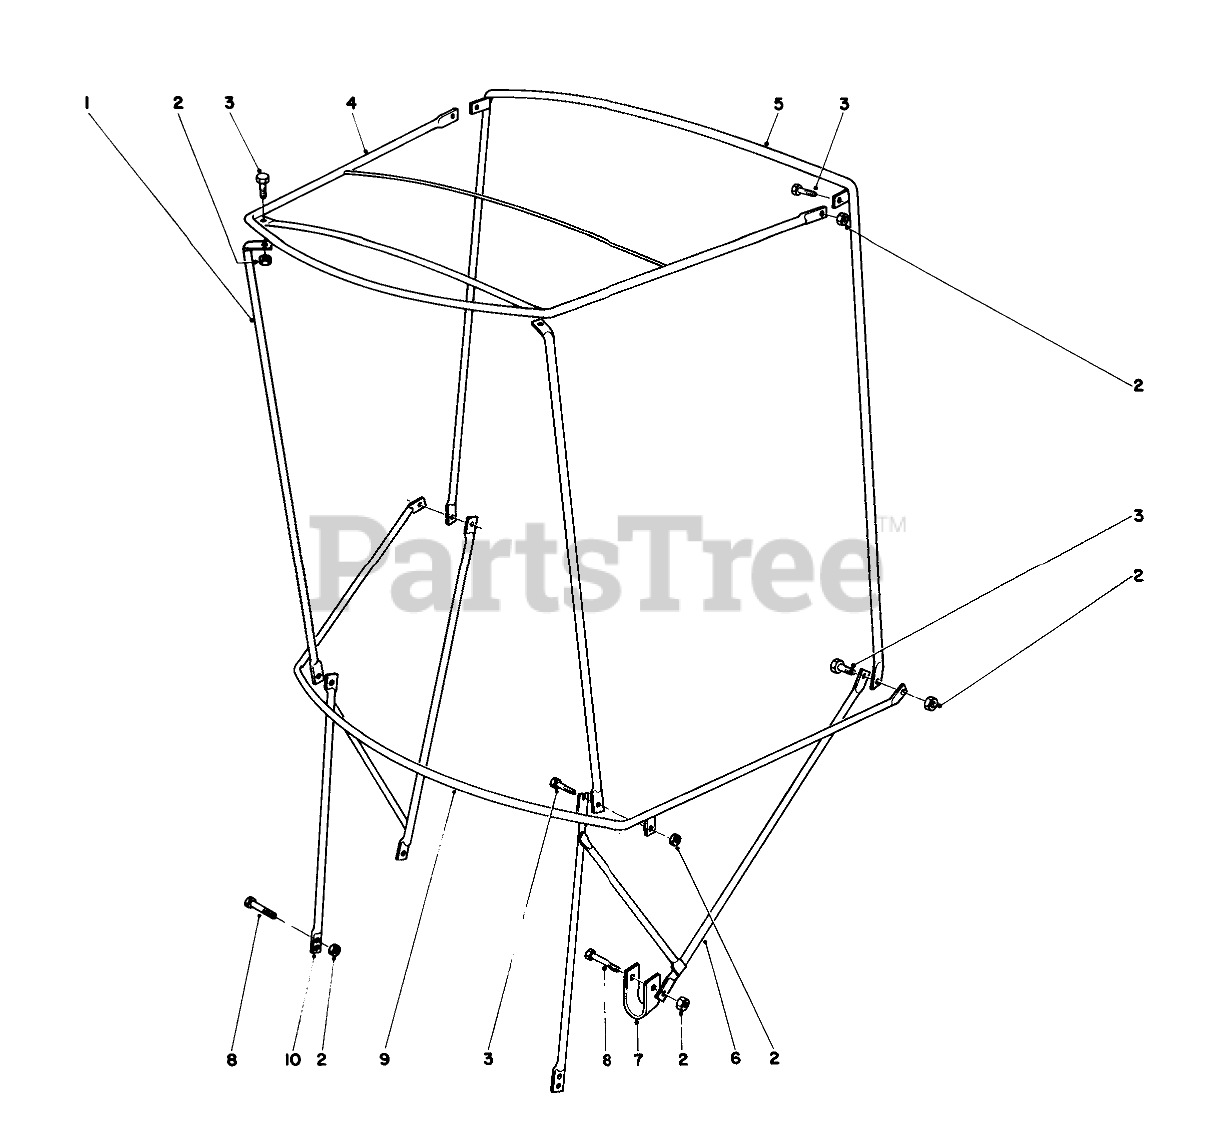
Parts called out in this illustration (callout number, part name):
2	NUT-LOCK
3	SCREW-HH
4	FRAME-TOP
5	BOW-VERTICAL, REAR
6	ATTACHING BRKT L
7	"U" Clamp
8	SCREW-HH
9	BOW-CURVED
10	ATTACHING BRKT R
